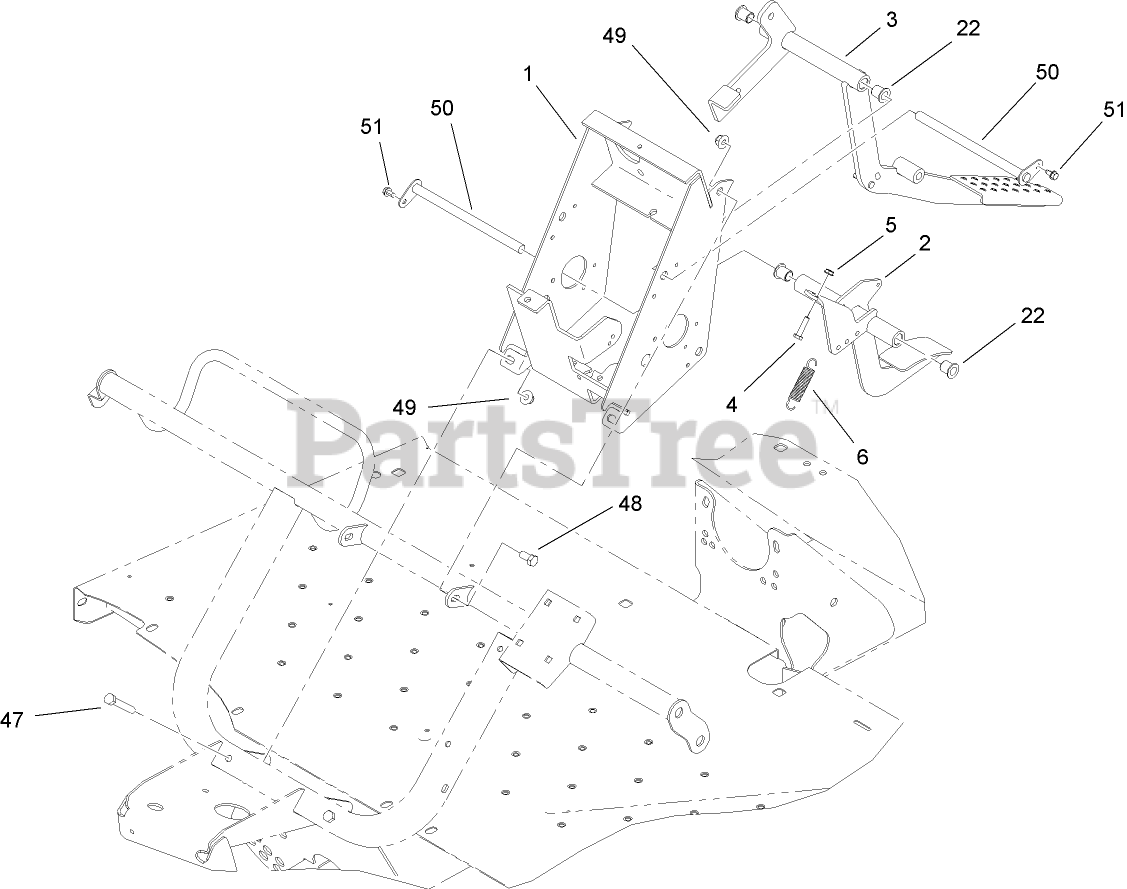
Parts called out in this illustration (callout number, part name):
1	PEDAL SUPPORT FRAME ASM
2	PEDAL-THROTTLE
3	PEDAL-BRAKE
4	SCREW-HH
5	NUT-KEPS
6	SPRING-RETURN, PEDAL
22	BUSHING-FLANGE
47	SCREW-HH
48	SCREW-HH
49	NUT-HF, NI
50	PIVOT-PEDAL
51	SCREW
